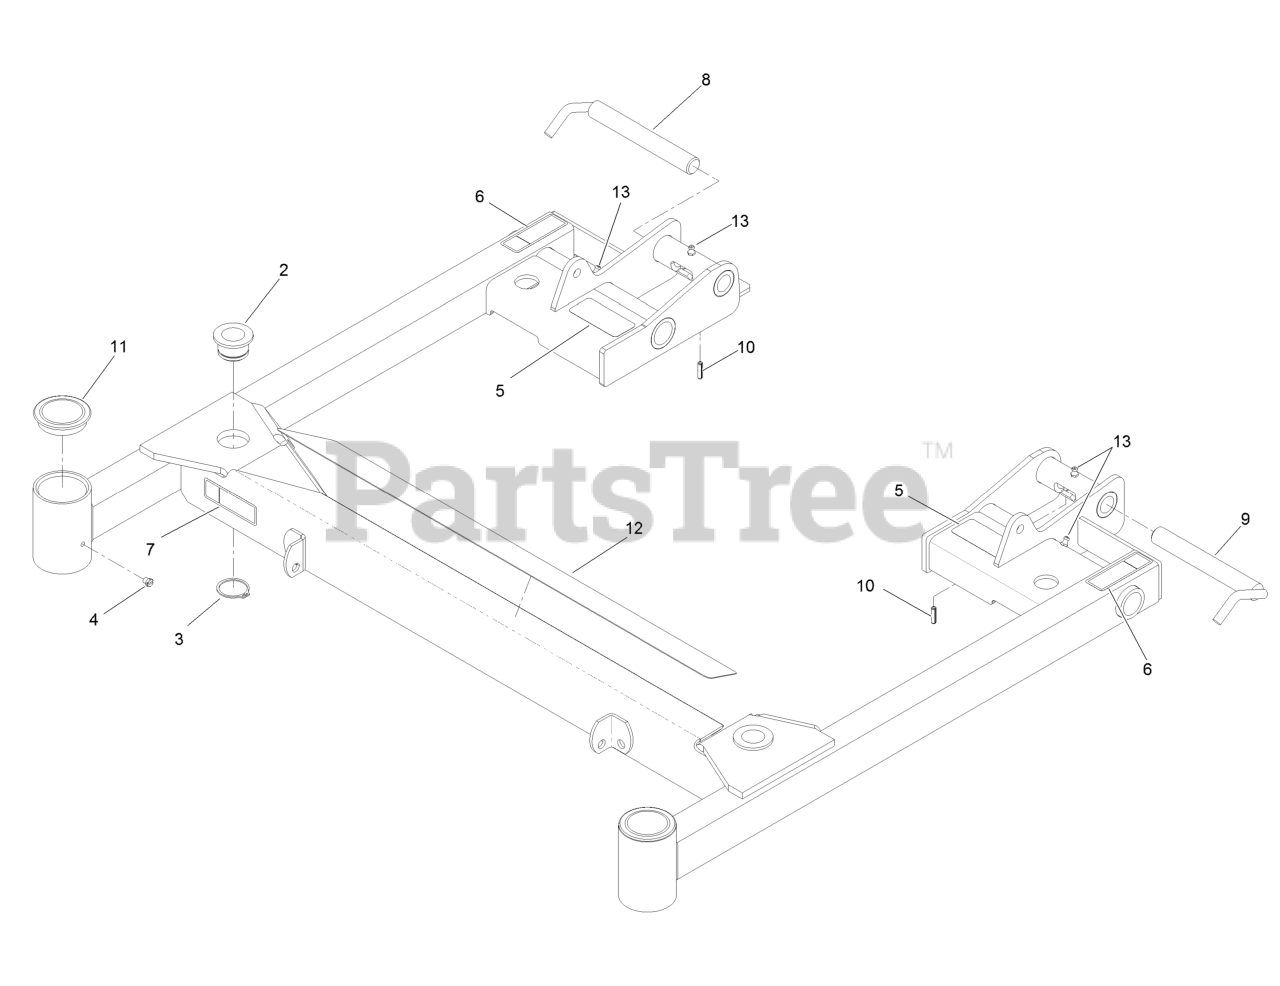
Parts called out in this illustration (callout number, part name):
2	Bushing-Support, Deck
3	Ring-Retaining
5	Decal-Warning
6	Decal-Warning, Folding Deck
7	Decal-Danger
8	Lock-Deck, RH
9	Lock-Deck, LH
10	Pin-Spring
11	Cap-Grease
12	Pad-Anti Skid
13	Fitting-Grease
